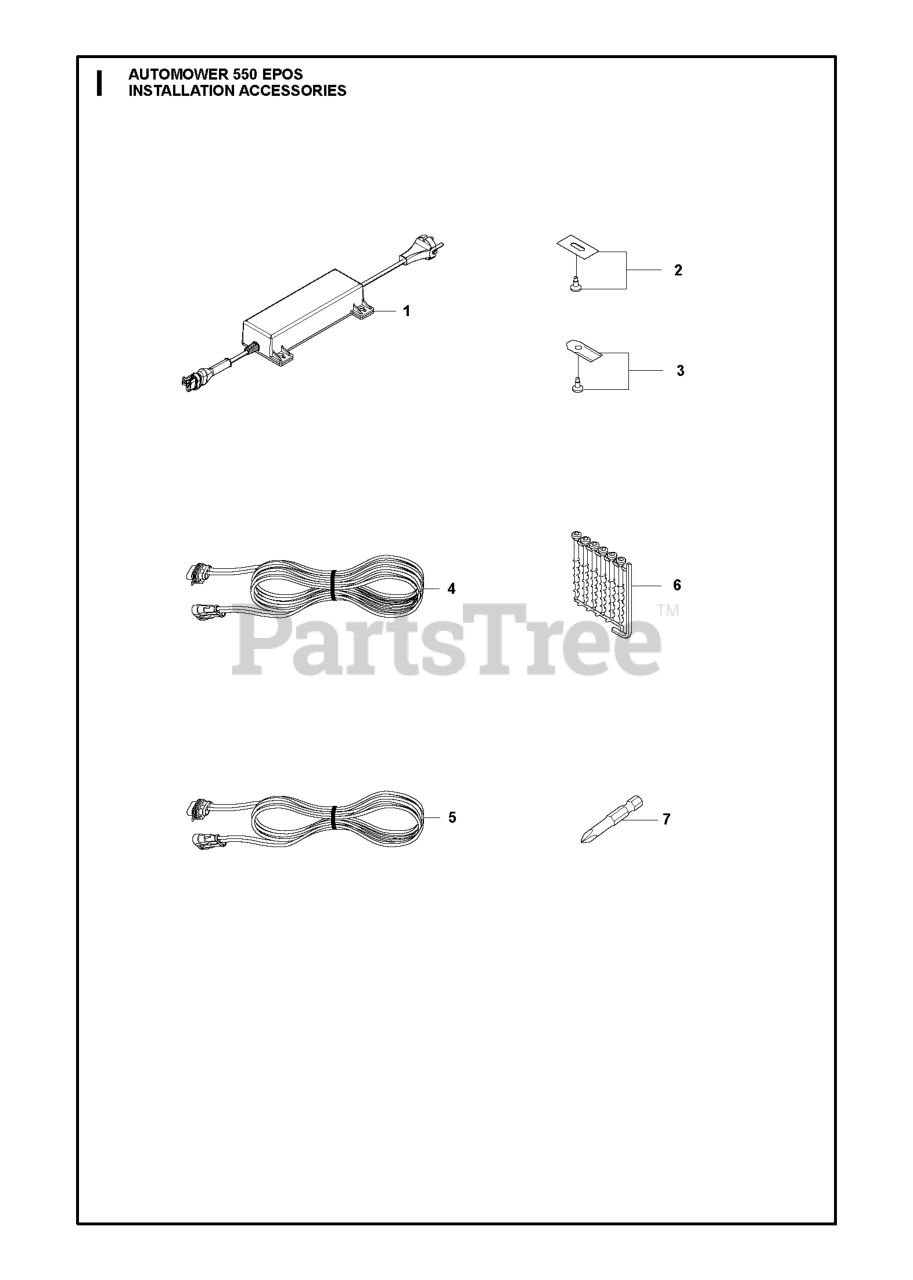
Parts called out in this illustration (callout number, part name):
1	Power Unit
3	HUS BLADE SET 45 PCS
3	HUS BLADE SET 9 PCS
3	HUS BLADE SET 300 PCS
4	CABLE LOW VOLTAGE CABLE P2 5-7
5	CABLE LOW VOLTAGE CABLE P2 5-7
6	Screws
7	WRENCH BITS CHANGING ROBOTIC B
